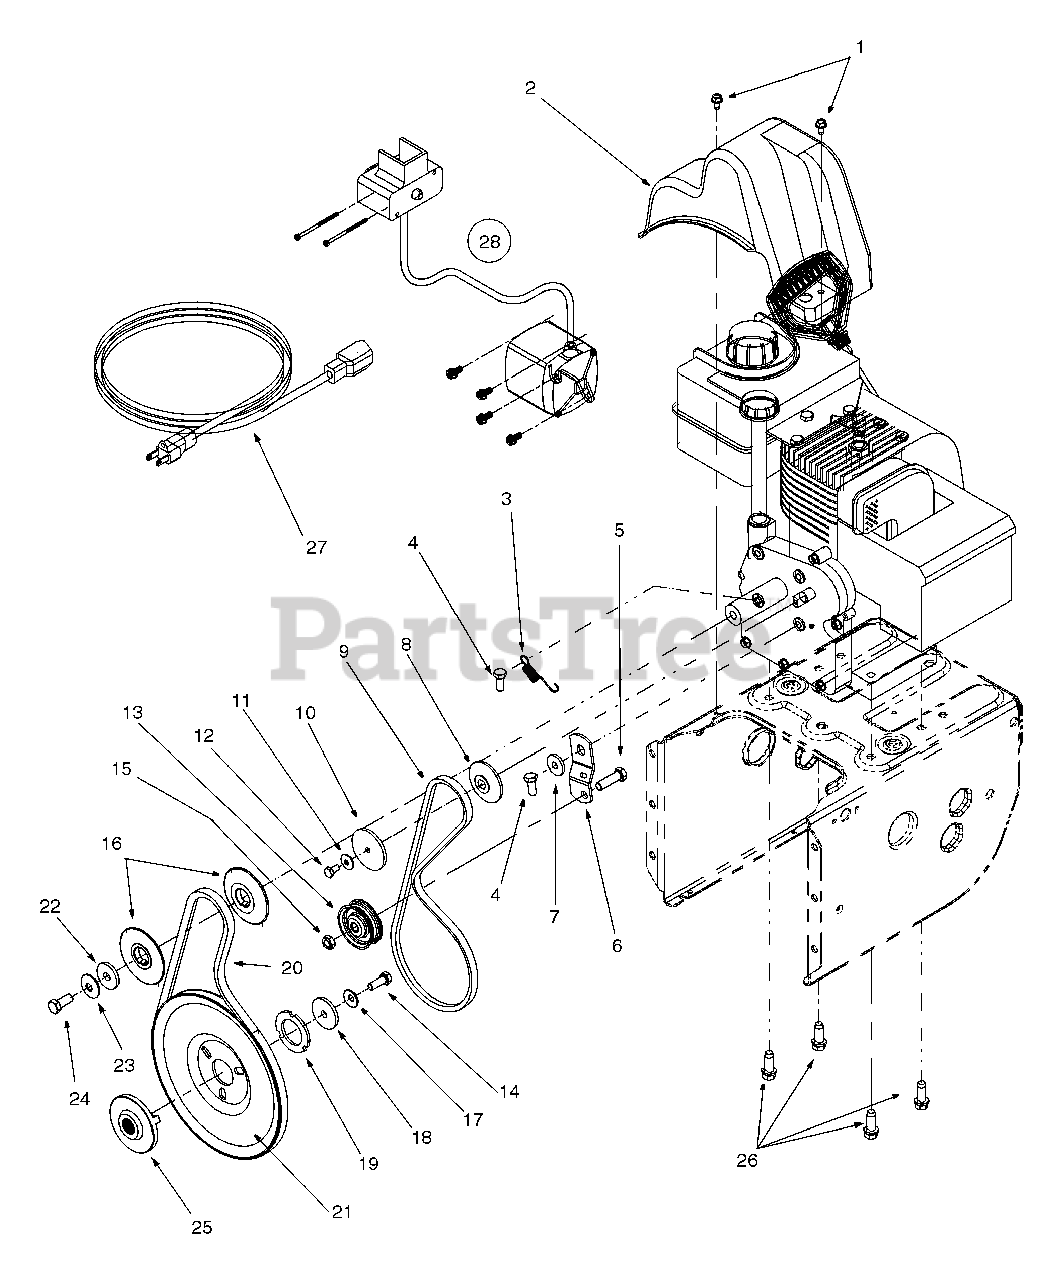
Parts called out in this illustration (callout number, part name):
1	Hex Washer Screw 1/4-20 x.625
2	Belt Cover
3	Extension Spring
4	Hex Screw 5/16-24 x .75
5	Hex Cap Screw 3/8-16 x 1.25
8	Pulley Half
9	V-Belt
10	Pulley Half
11	Bell Washer
12	Hex Cap Screw 1/4-28 x .50
13	Flat Idler
14	Lock Cap Screw 5/16-24
15	Lock Jam Nut 3/8-16
16	Pulley Half
17	Bell Washer
18	Flat Washer
19	Washer
20	Belt
21	Auger Pulley
22	Flat Washer
23	Bell Washer
24	Hex Cap Screw 3/8-24
25	Pulley
26	Hex Washer Screw 3/8-16 x 1.0
27	Extension Cord
28	Electric Start Kit
